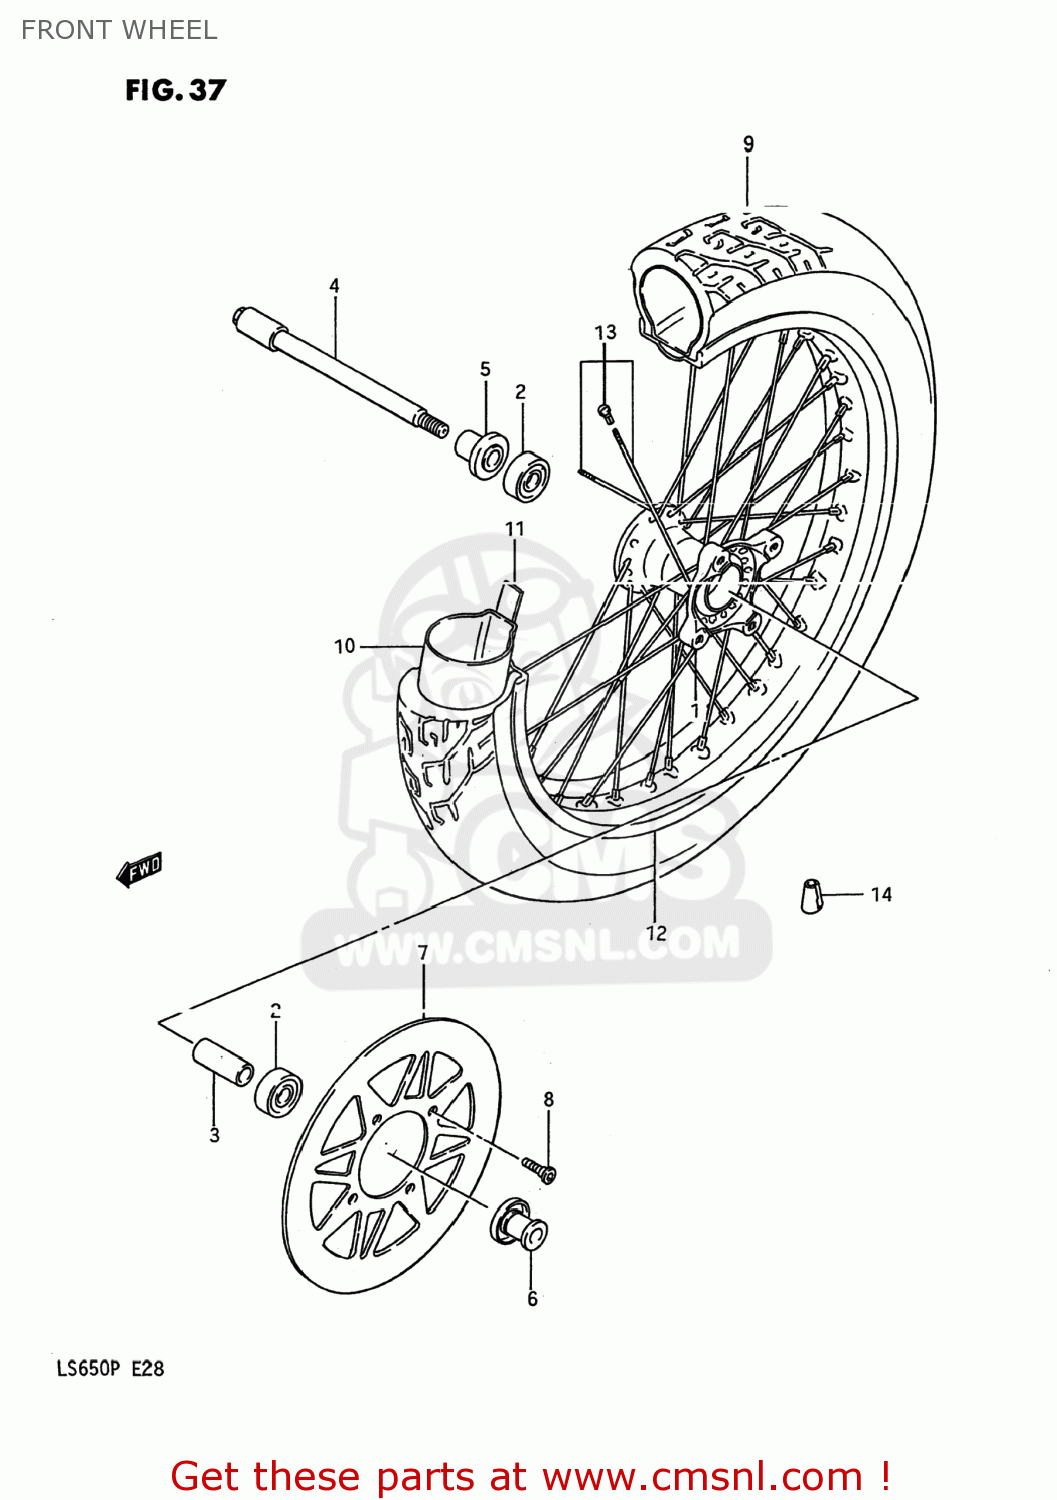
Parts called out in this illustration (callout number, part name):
1	HUB,FR WHEEL
2	BEARING
3	SPACER(15.3X21.7X56)
4	AXLE,FR
5	SPACER,FR AXLE,R
6	SPACER,FR AXLE,L
7	DISC,FR BRAKE
8	BOLT(8X25.5)
9	TIRE,FRONT 100/90-19.5
10	TUBE
11	PROTECTOR,WHL INR TUBE
12	RIM,FR WHEEL WM(2.15X19)
13	SPOKE SET,FRONT
14	BALANCER,WHEEL
